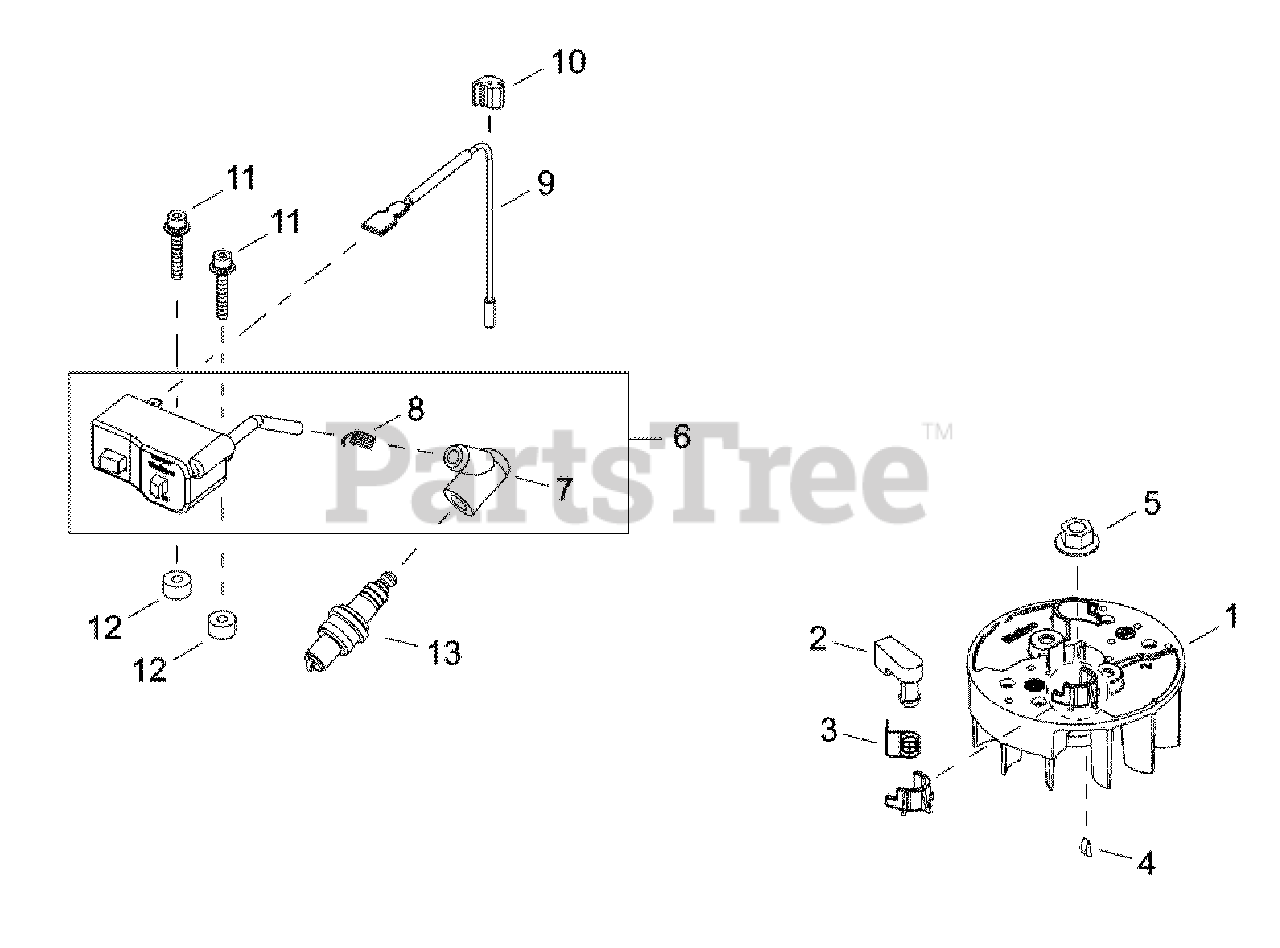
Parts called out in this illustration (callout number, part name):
1	FLYWHEEL
2	PAWL, STARTER
3	SPRING
4	KEY - 3X10
5	NUT - 8
6	IGNITION COIL ASSY
7	CAP, SPARK PLUG
8	TERMINAL, SPARK PLUG CAP
9	LEAD - IGNITION
10	GROMMET
11	SCREW - 4X26
12	INSULATOR
13	SPARK PLUG -- CMR-5H
